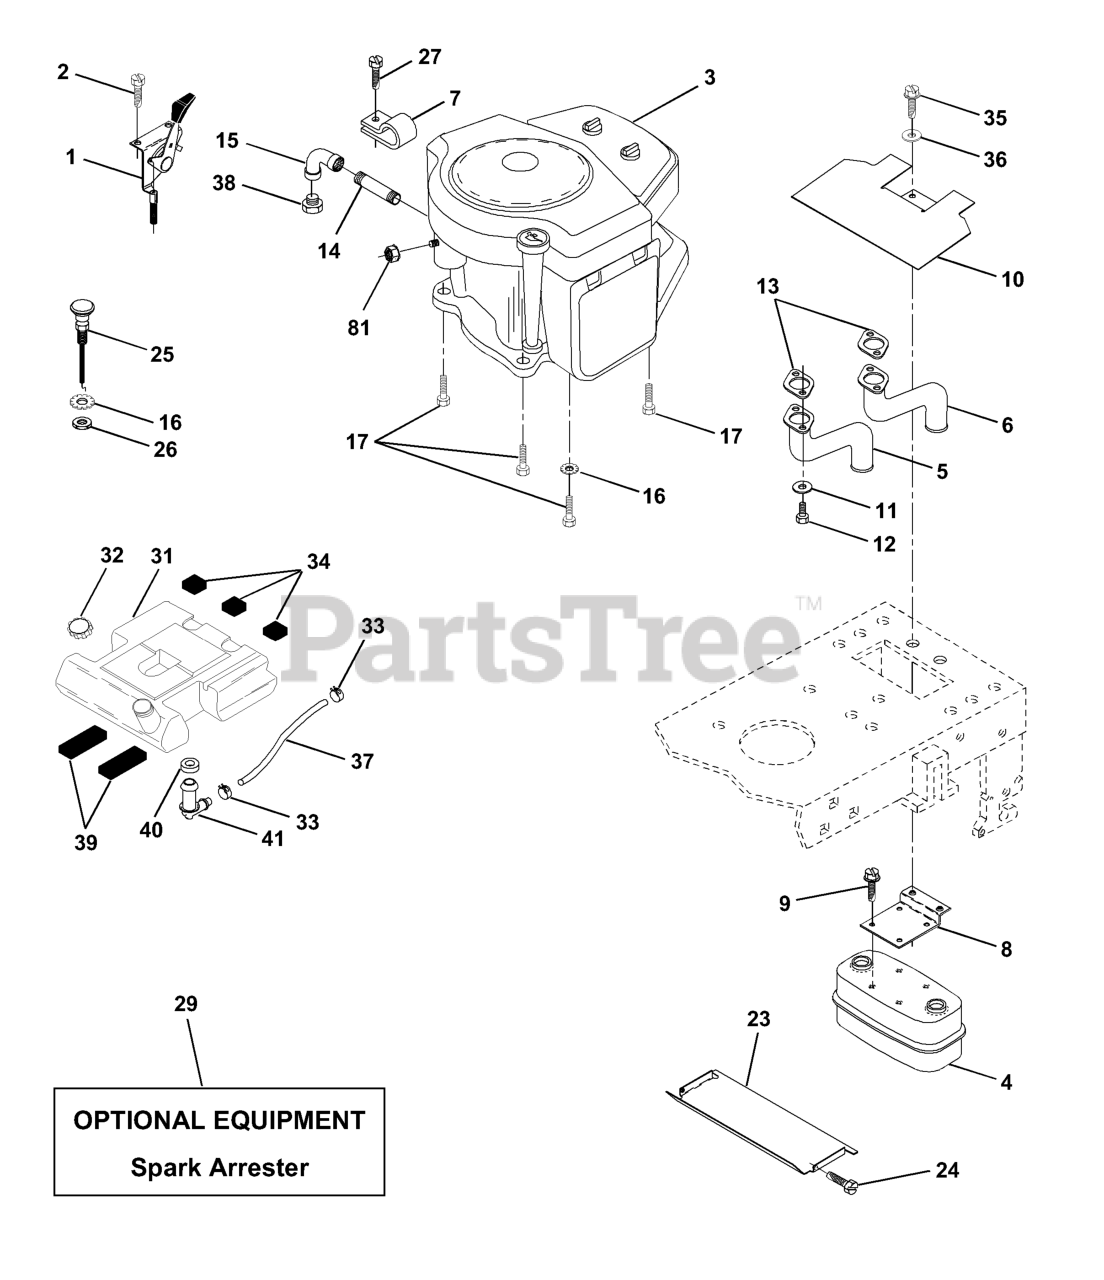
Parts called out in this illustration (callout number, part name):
1	CONTROL.THROT.RH.BLK.FLG.44.75
2	SCREW LT
4	MUFFLER
5	EXHAUST ASM. LEFT
6	EXHAUST ASM. RIGHT
8	BRACKET MUFFLER
9	SCREW ST
10	SHIELD HEAT LT
11	LOCKWASHER
12	BOLT
13	Muffler Gasket
14	Nipple Pipe 3/8 Npt X 4-1/2"
15	ELBOW
16	LOCKWASHER
17	SCREW LT
23	HEAT SHIELD
25	CONTROL.CHOKE.51.00.BLK.W/BEND
26	NUT
29	KIT.SPARK ARRESTOR 794945 B&S
31	FUEL TANK
32	FUEL CAP
33	HOSE CLAMP
34	PAD-SPACER LT
35	SCREW.THDROL.5/16-18X3/4.TTY
36	WASHER
37	FUEL LINE 54"
38	Plug Oil Drain
39	PAD IDLER TI
40	BUSHING OUTLET T
41	STEM FUEL TANK
81	NUT
